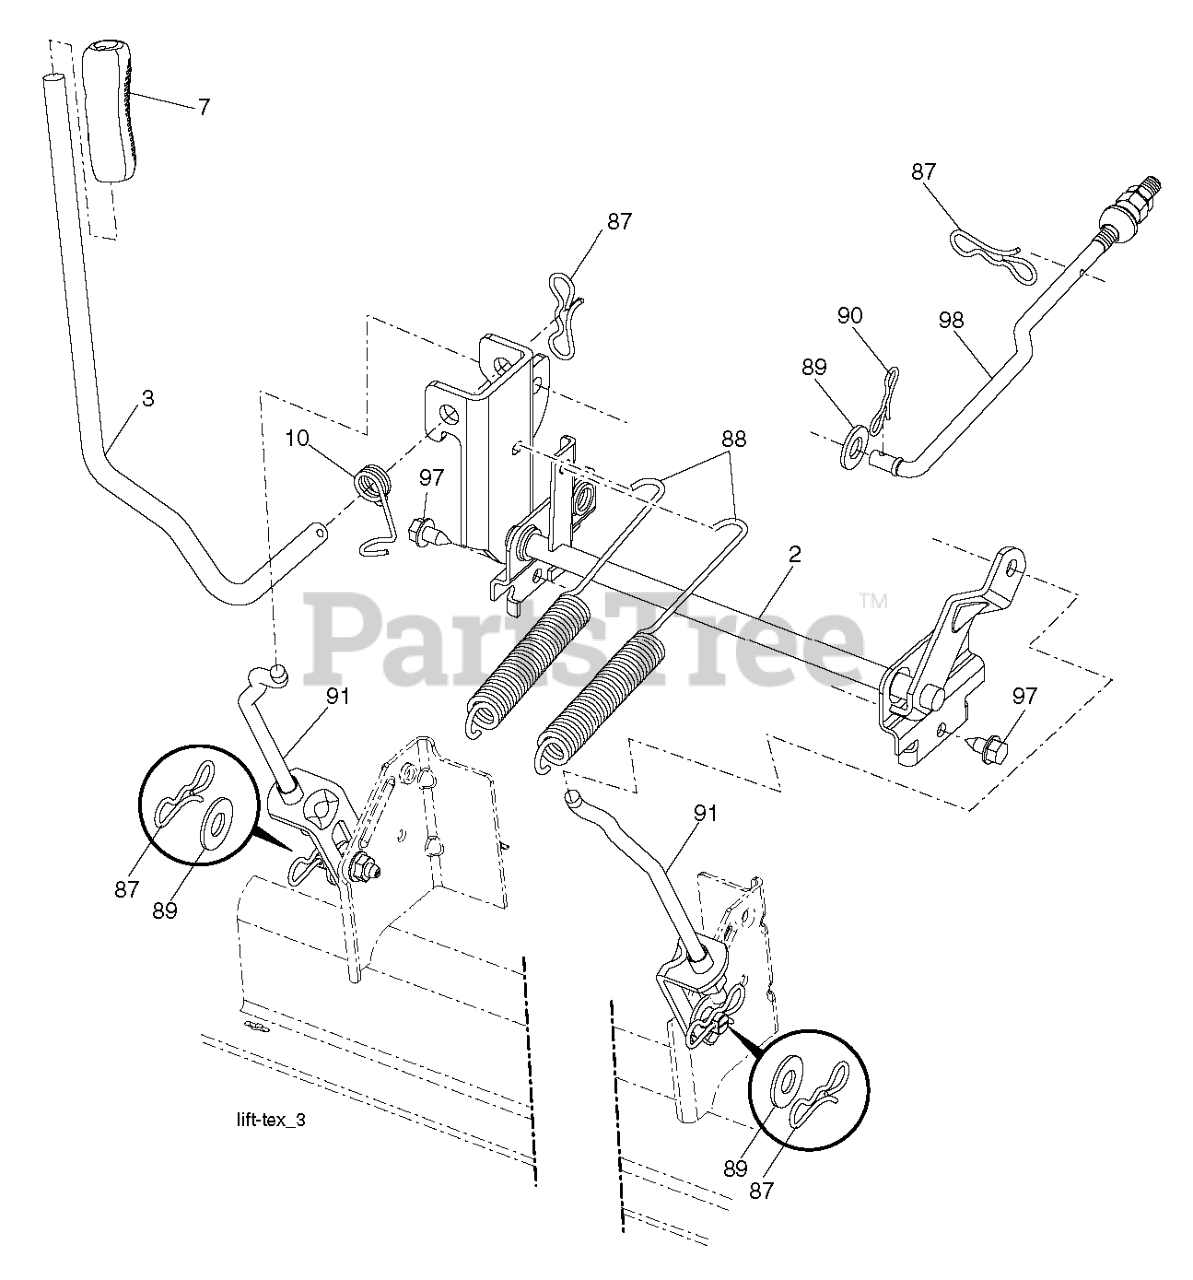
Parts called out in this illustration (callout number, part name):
2	SHAFT.ASM.CROSS.LIFT
3	LEVER.LIFT.HANDLE.LT
7	GRIP.HANDLE.LIFT.PVC.BLACK
10	SPRING.TORSION.LIFT.HANDLE
87	PIN.COTTER.7/16.BOW TI.
88	SPRING.LIFT.ASSIST
89	WASHER.CLEAR.ZINC
90	PIN.COTTER.5/16.BOW TI
91	LINK.ASM.LIFT.REAR
97	SCREW, 3/8-16X3/4
98	LINK.ASM.SUSP.FRONT.MWR.10.5
